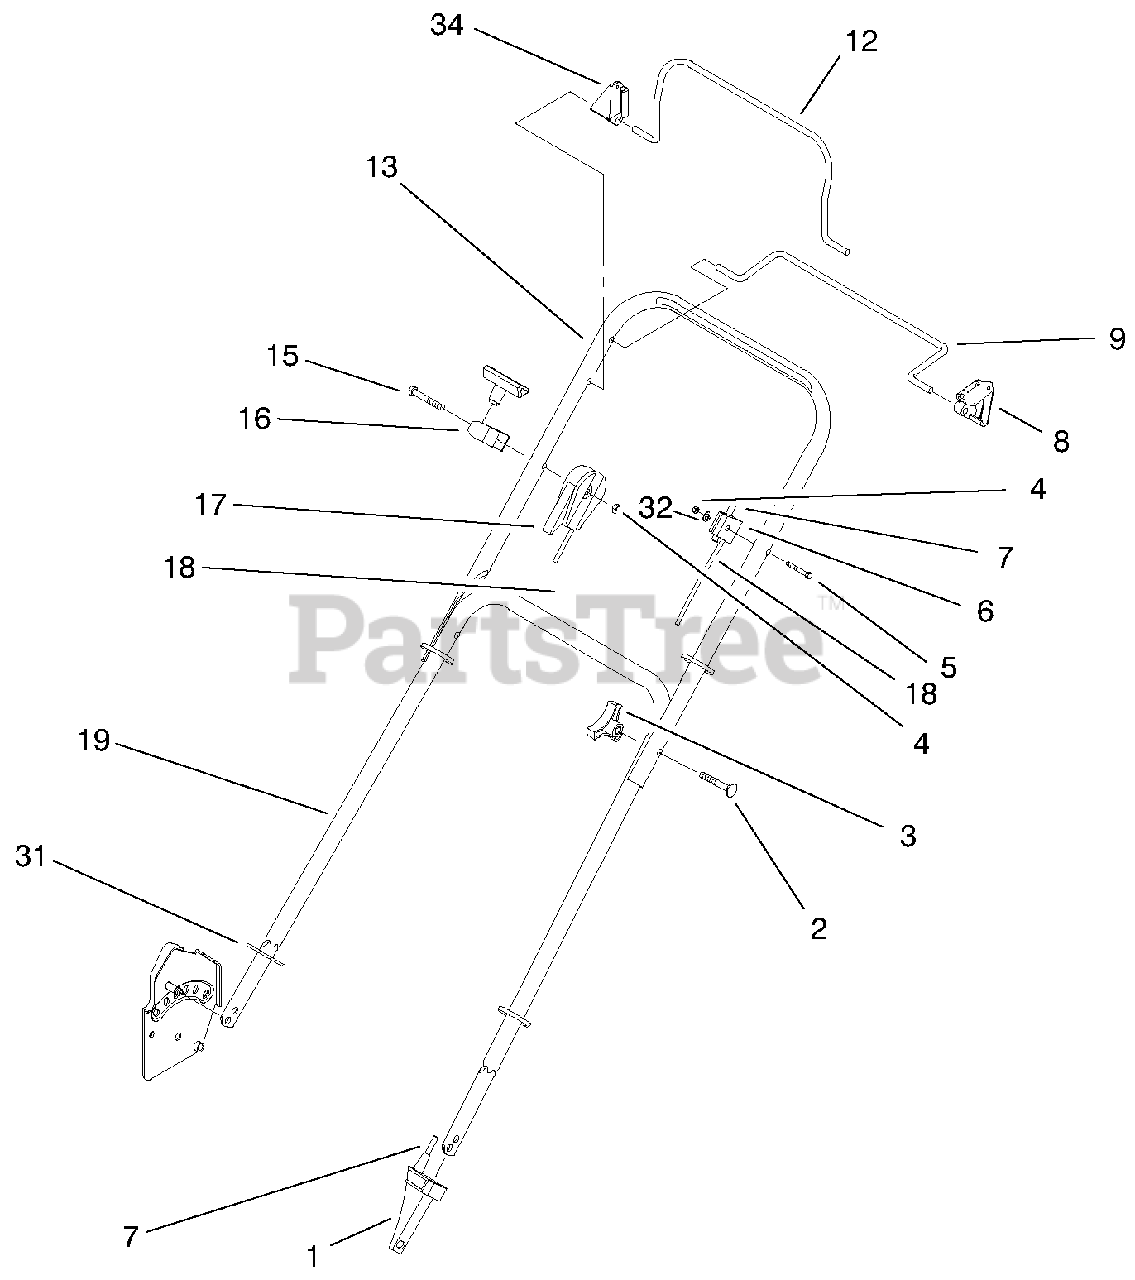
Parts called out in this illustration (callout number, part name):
1	Anchor-Cable
2	Screw-Handle
3	Knob
4	Nut-Lock
5	Screw-Handle
6	Anchor-Cable
7	Cable-Traction
8	Stop-Pivot
9	Bail-Sp Control
12	Bail-Flywheel Brake
13	Handle Section-Upper
16	Guide-Rope
17	Cable-Throttle
18	ASM-Brake Cable
19	Handle Section-Lower
25	ASM-Bag & Adapter
26	ASM-Chute & Support
27	Hanger-Wide
28	Hanger-Clamp
31	Handle-Guard
32	Washer-Flat
34	Stop-Bail
